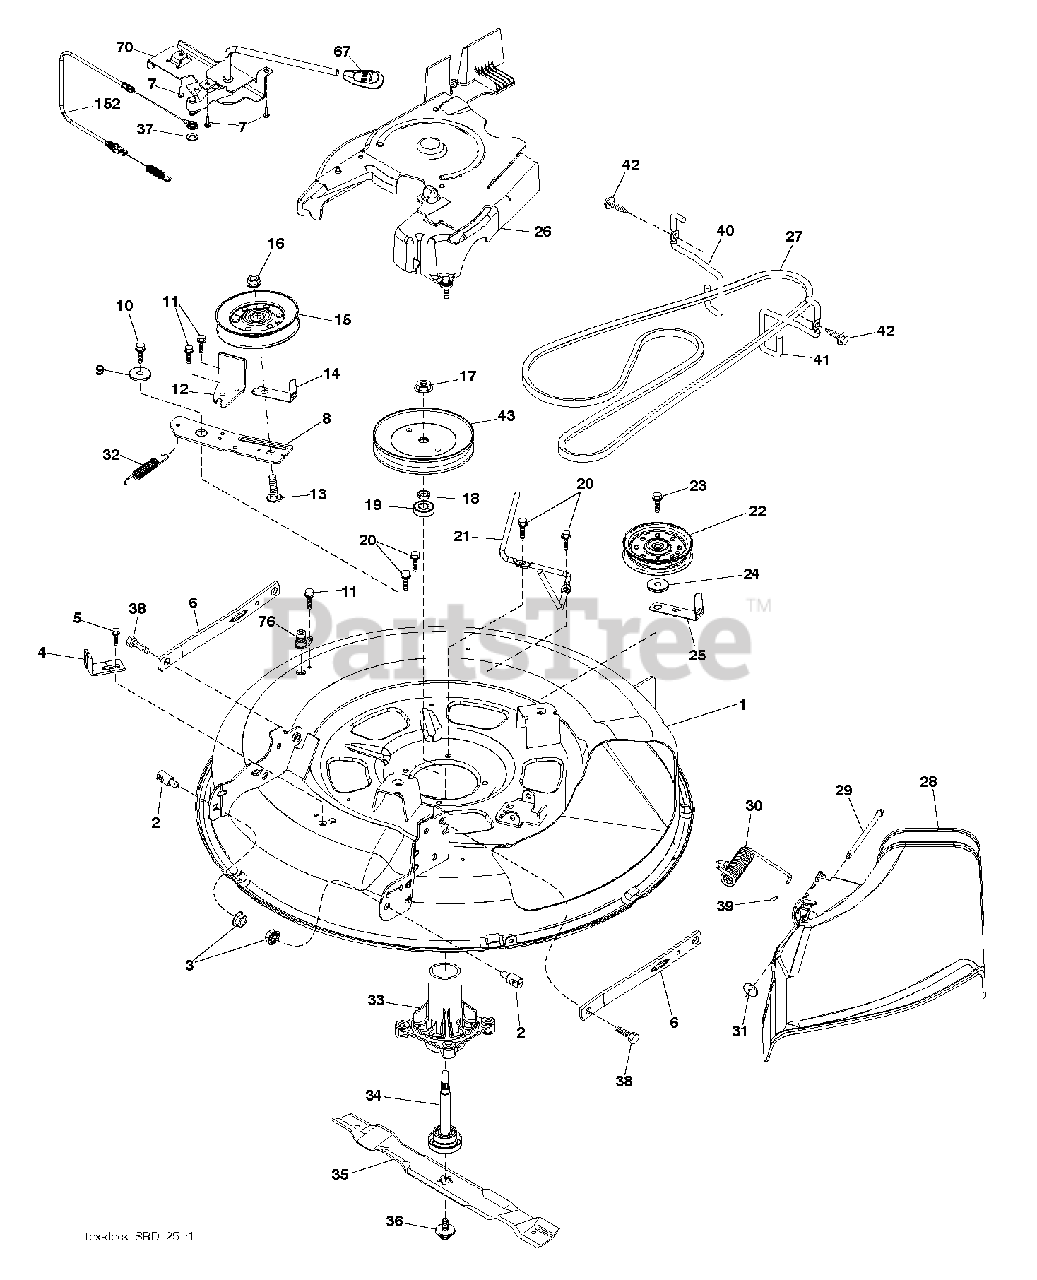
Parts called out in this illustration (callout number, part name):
1	DECK KIT SVC 30"BLUE
2	STUD.FASTNER.W/ANTI-ROTATE
3	NUT LOCK HEX FLANGE 5/16-18
4	BRACKET.CLUTCH.CABLE
5	BOLT.5/16HEX.WHS.HD
6	ARMS.SUSP.MOWER.REAR.SRD
7	SCREW.#10 X 0.750.BOS (2 2)
8	ARM.IDLER.30"SRD
9	SPACER.RETAINER
10	SCREW 3/8-16X1
11	SCREW.1/4-20X5/8
12	ARM BRAKE MOWER RH
13	BOLT.3/8-16X1.50
15	PULLEY.IDLER.4.25
16	NUT LOCK FLG 3/8-16 UNC
17	NUT.FLANGE.LOCK.TOP
18	WASHER.SPACER.MANDREL
19	BEARING
20	SCREW, WASHER HEAD
21	KEEPER.BELT.MANDREL.30"
22	PULLEY.IDLER.FLAT.46.PR.DR.
23	SCREW LT
24	WASHER
25	KEEPER.BELT.30"SRD
26	COVER.ASM.MANDREL.30"
27	V-BELT.DRIVE.MOWER.30"
28	SHIELD.DEFLECT.MWR.30S.BLACK
29	PIN.HINGE.30".SRD
30	SPRING.TORSION.DEFLECT
31	NUT PUSH M
32	SPRING RETURN
33	HOUSING.MANDREL.4PT.
34	SHAFT.ASM.MDRL.N/GREASE.38
35	BLADE, MULCH.LRV30
36	BOLT.WASHER.ASM.7/16-2
37	WASHER
38	BOLT.SHOULDER
39	CAP-SLEEVE LT
40	KEEPER.BELT.ENGINE.LH.LT.SRD
41	KEEPER.BELT.ENGINE.RH.LT.SRD
42	SCREW, 3/8-16X3/4
43	PULLEY, MANDREL 6.5 PD
67	HANDLE.CLUTCH.CABLE.LT
70	CLUTCH.ASM.MANUAL.LT.PRED
76	PORT.WASHOUT
152	CABLE.CLUTCH.MANUAL.
